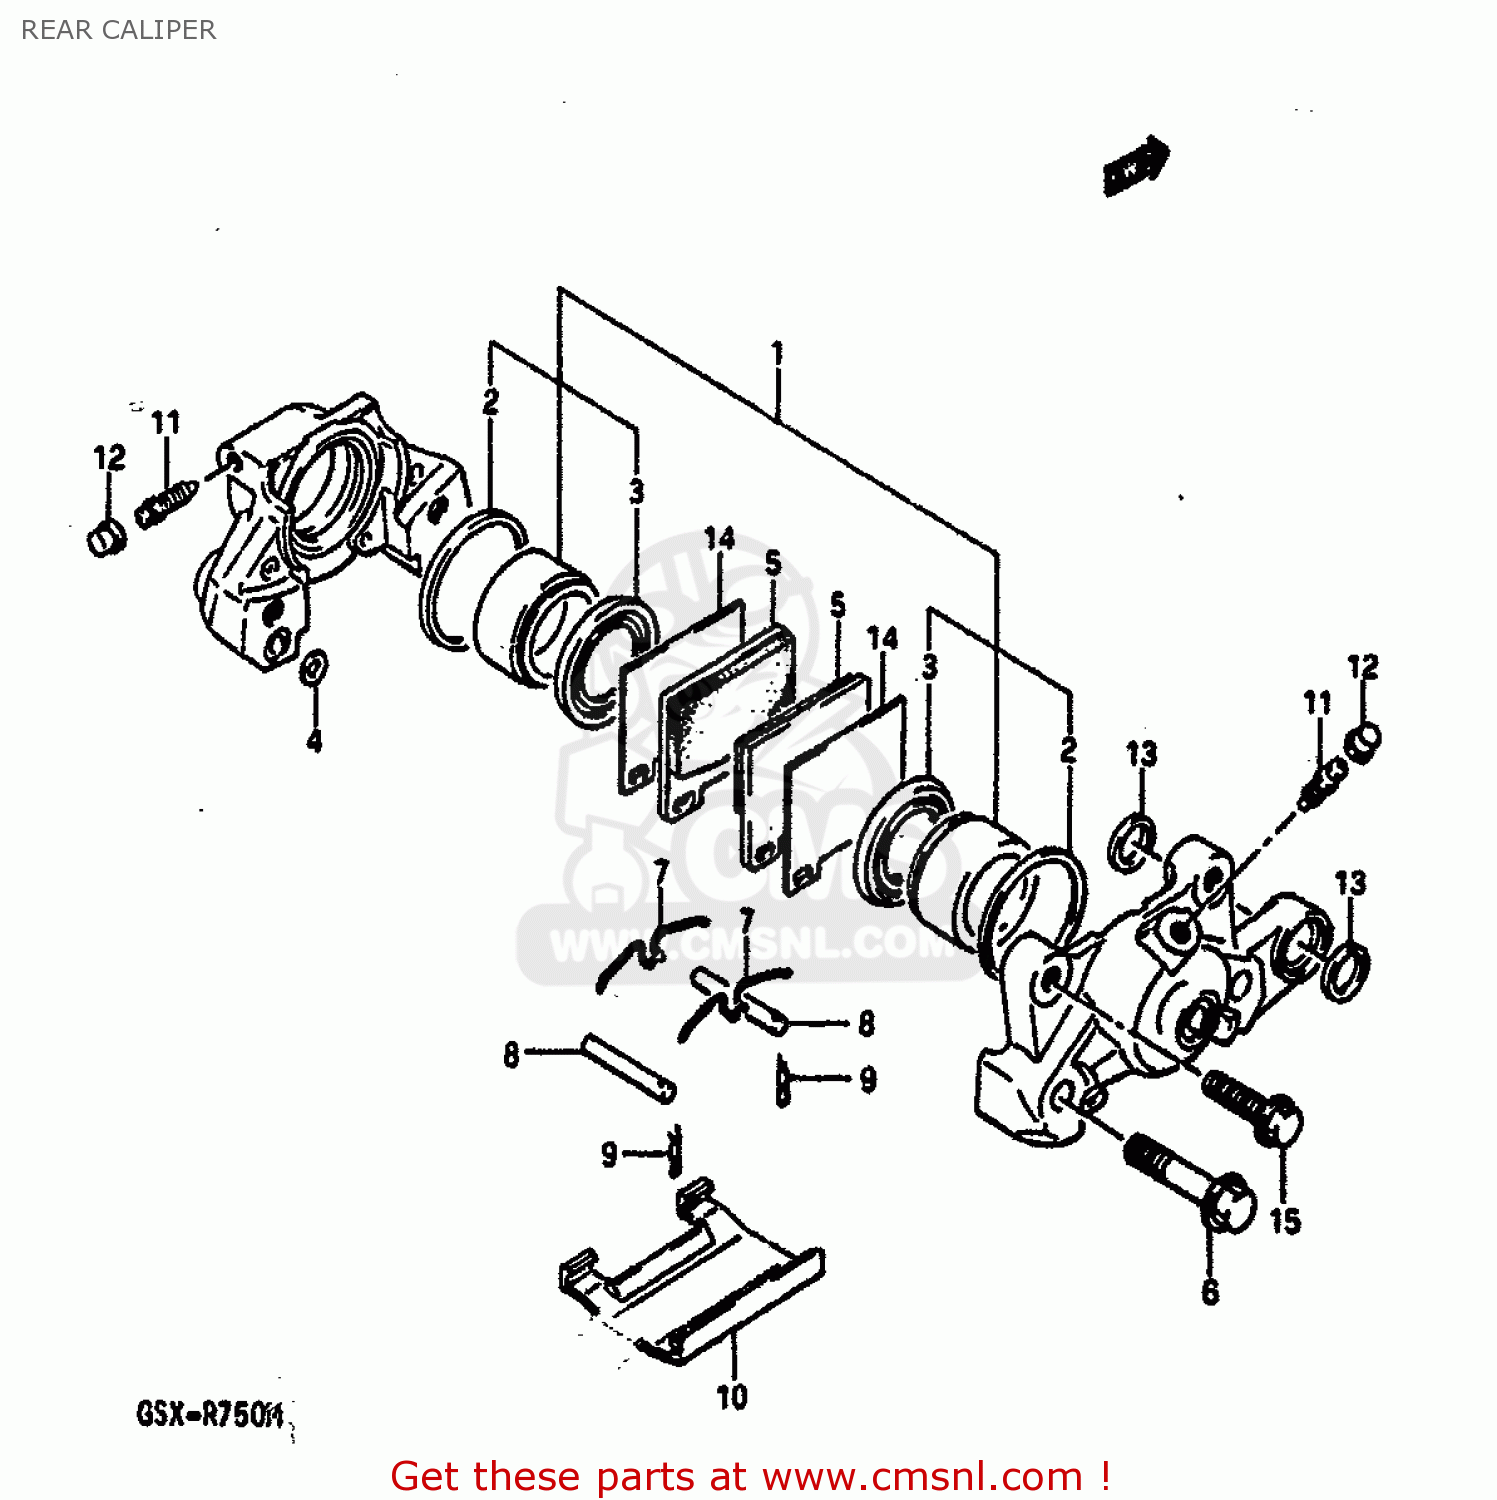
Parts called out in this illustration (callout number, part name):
1	PISTON SET
2	SEAL,PISTON
3	BOOT
4	SEAL,JOINT
5	PAD,BRAKE
6	BOLT
7	SPRING
8	PIN,PAD
9	CLIP,PAD PIN
10	COVER
11	BLEEDER
12	CAP,BREATHER
13	SEAL,RR CUSHION ROD LWR
14	SHIM,PAD
15	BOLT
